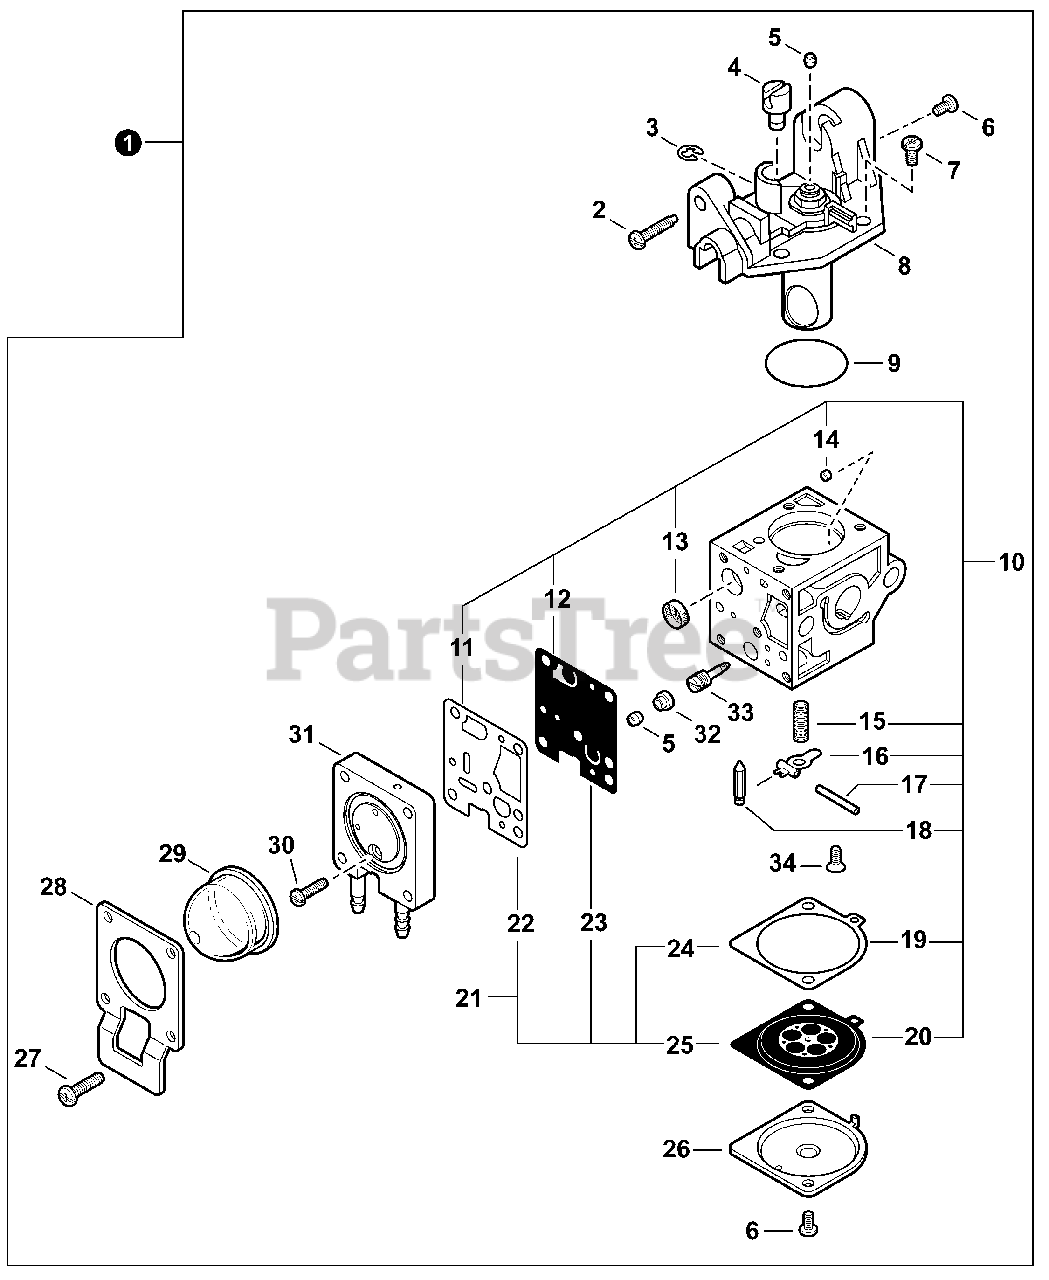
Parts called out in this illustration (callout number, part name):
1	CARBURETOR RB-K113
2	SCREW, THROTTLE ADJUST
5	CAP, LIMITER
8	COVER ASSY, ROTOR
10	REPAIR KIT, CARBURETOR
11	GASKET, PUMP
12	DIAPHRAGM, PUMP
13	SCREEN, FUEL INLET
14	GUIDE, ROLLER
15	SPRING, METERING LEVER
16	LEVER, METERING
17	PIN, METERING LEVER
18	VALVE, INLET NEEDLE
19	GASKET, METERING DIAPHRAGM
20	DIAPHRAGM, METERING
21	GASKET / DIAPHRAGM KIT
22	GASKET, PUMP
23	DIAPHRAGM, PUMP
24	GASKET, METERING DIAPHRAGM
25	DIAPHRAGM, METERING
26	COVER, METERING DIAPHRAGM
28	RETAINER, PURGE BULB
29	BULB, PURGE
31	BODY ASSY, PURGE
33	NEEDLE, HIGH SPEED
